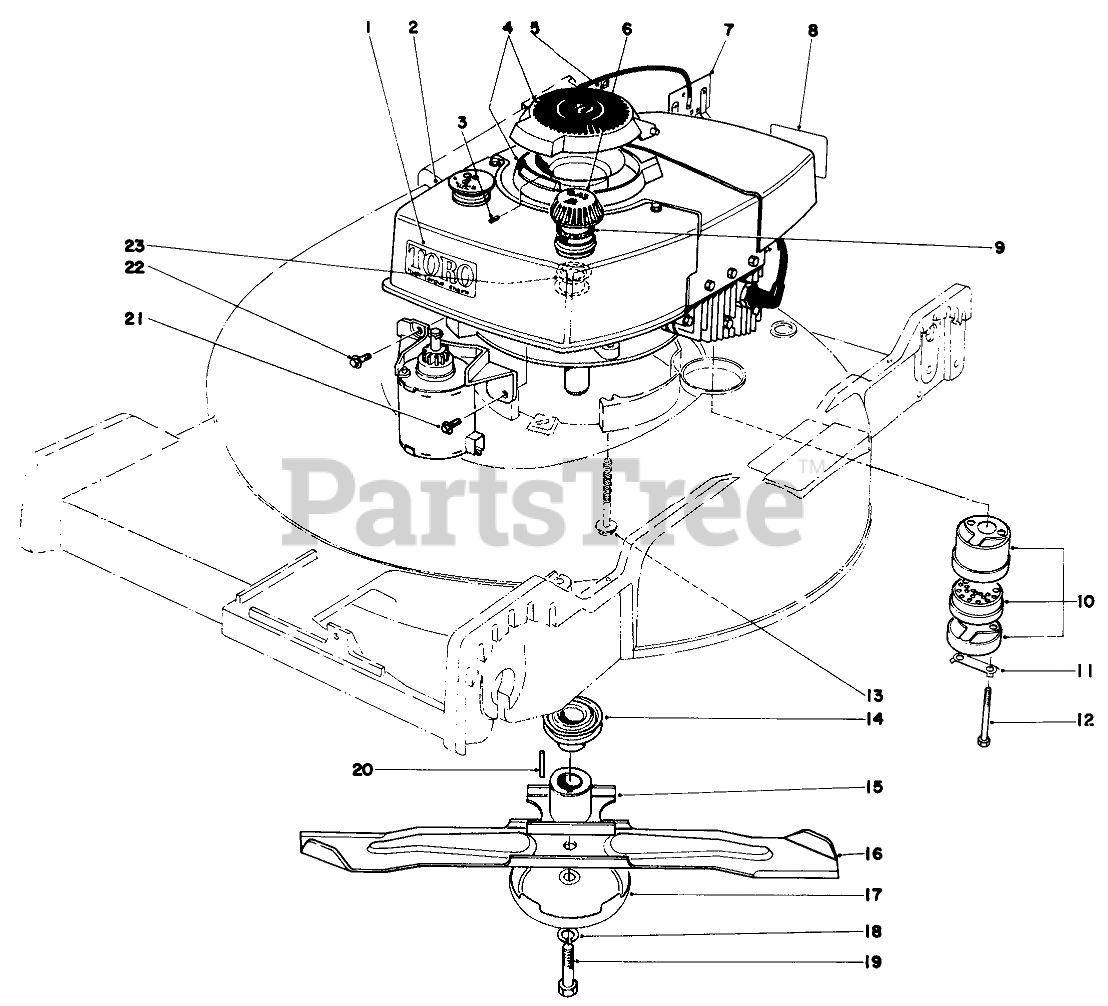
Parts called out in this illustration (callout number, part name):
1	High Torque
2	Engine
3	SPRING PIN
4	Cover
5	WIRE CLIP
6	Gas Cap Assembly (Incl. Ref. #9 & 23)
7	SWITCH & TERM BLK CVR
8	Decal Maintenance
9	GASKET
10	Muffler Assembly (Incl. Ref. #11 & 12)
11	CLIP - LOCKING
12	SCREW-HH
13	3/8-16 X 2-3/4 CAPSCR
14	DRIVER PULLEY
15	BLADE RETAINER WA(BLACK)
16	Blade
17	AntiScalp Cup
18	WASHER-LOCK
19	BLADE SCREW
20	KEY-SQUARE
21	SCREW
22	Screw
23	GAS CAP BAFFLE
